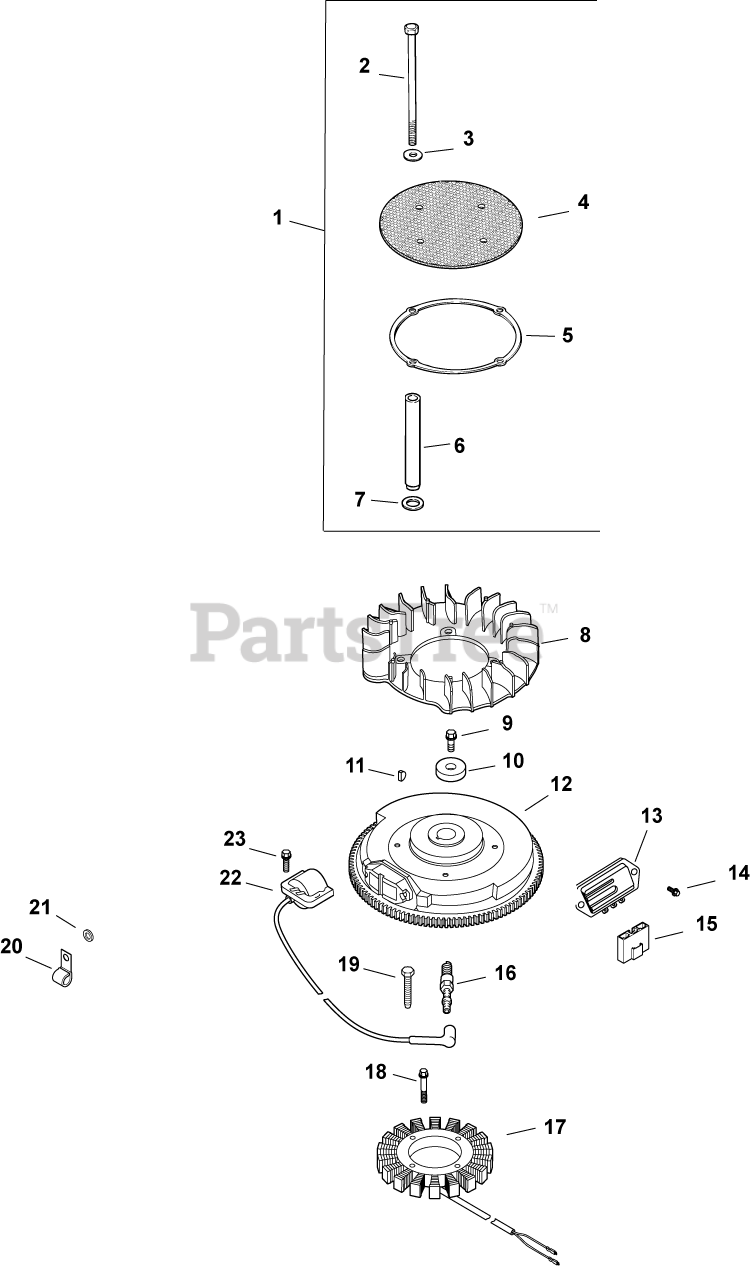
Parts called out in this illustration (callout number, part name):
1	KIT, CHOPPER SCREEN
2	SCREW, CAP M6X1.0X99.5
3	WASHER, FLAT 1/4" (O.D. 5/8")
4	SCREEN, GRASS
5	RING, SUPPORT USE 25 141 08-S
7	WASHER, SPRING 10 MM
9	SCREW, FLG M10X1.5X45 - (#25086361S)
10	WASHER, FLAT 13/32"
11	KEY, 3/16" X 5/8"
13	REG/RECT-15 AMP (KM)-USE 41 403 10-S
14	SCREW, HEX FLANGE HI-LO
15	CONNECTOR, BODY (KM)-USE 25 155 41-S
16	PLUG, SPARK (STD)
17	KIT, 15 / 20 AMP STATOR
18	SCREW, SKT SET #10-24X1/4"
19	SCREW, M5X0.8X25 - (#25086402S)
20	CLIP, CABLE
21	WASHER, FLAT 1/4" (O.D. 1/2")
22	KIT, MODULE IGNTN (CDI FIXED)
23	SCREW, FLG THD FRM M5X.8X20-(#25086399S)
